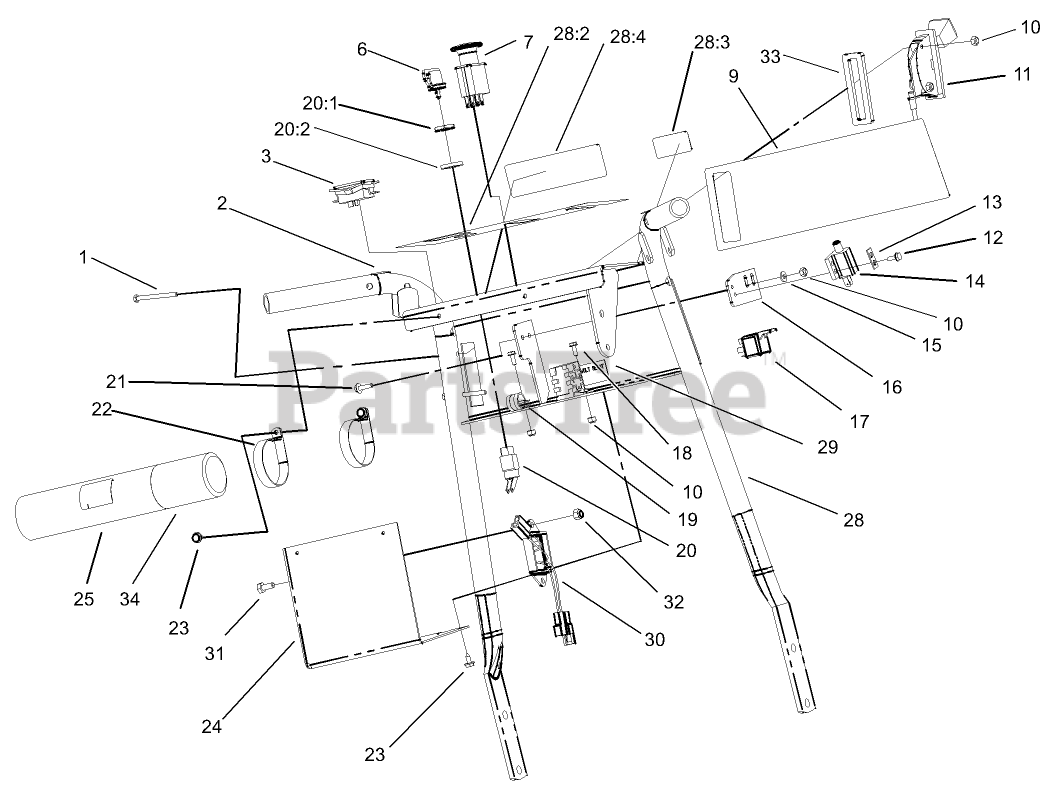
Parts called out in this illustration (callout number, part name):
1	SCREW-SHH
2	DECAL-LOCK, NEUTRAL
3	HOURMETER
6	KEY-IGNITION
7	SWITCH-PTO
9	DECAL-CONTROL, THROTTLE
10	NUT-LOCK, NI
11	CONTROL-THROTTLE
12	SCREW-TAPTITE
13	PLATE-SWITCH
14	SWITCH-POLE, SINGLE
15	WASHER-FLAT
16	PLATE-MOUNTING, SWITCH
18	SCREW-HWH
19	CLAMP-R
20	SWITCH-ON / OFF
20:1	NUT-HH
20:2	WASHER-TOOTH, INTERNAL
21	SCREW-HWH
22	CLAMP-R
23	SCREW-HWHTF
24	BRACKET-COVER
25	TUBE-MANUAL
28	HANDLE ASM
28:2	DECAL-PANEL, CONTROL
28:3	DECAL-PROTECTION, EAR
28:4	DECAL-WARNING
29	DECAL-RELAY, 24 VOLT
30	Module-Filter
31	SCREW-HH
32	NUT-LOCK, NI
33	GASKET-THROTTLE
34	CAP-HOUSING
